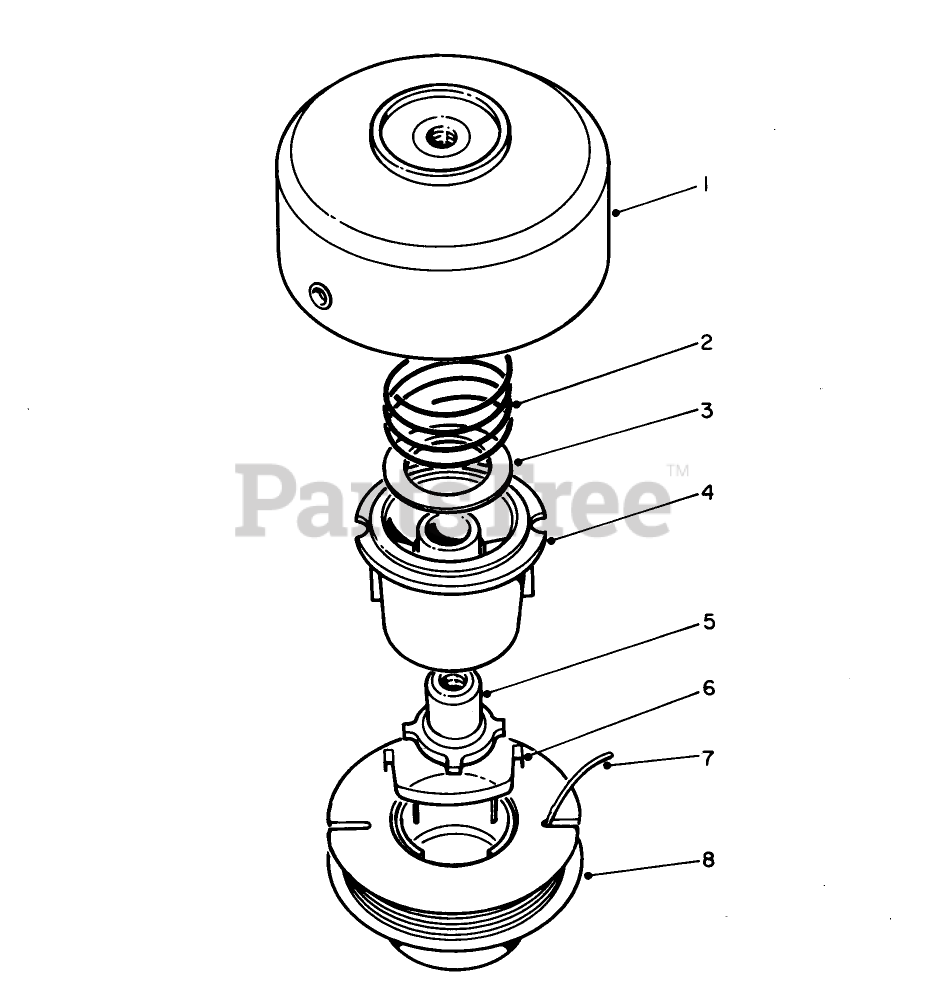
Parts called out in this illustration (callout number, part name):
1	Drum Assembly
2	SPRING
3	WASHER-FLAT
4	SPOOL CORE
5	LH DRIVER
6	SADDLE-SPOOL CAP
7	#1 BULK SPOOL .095
8	Prewound Spool
